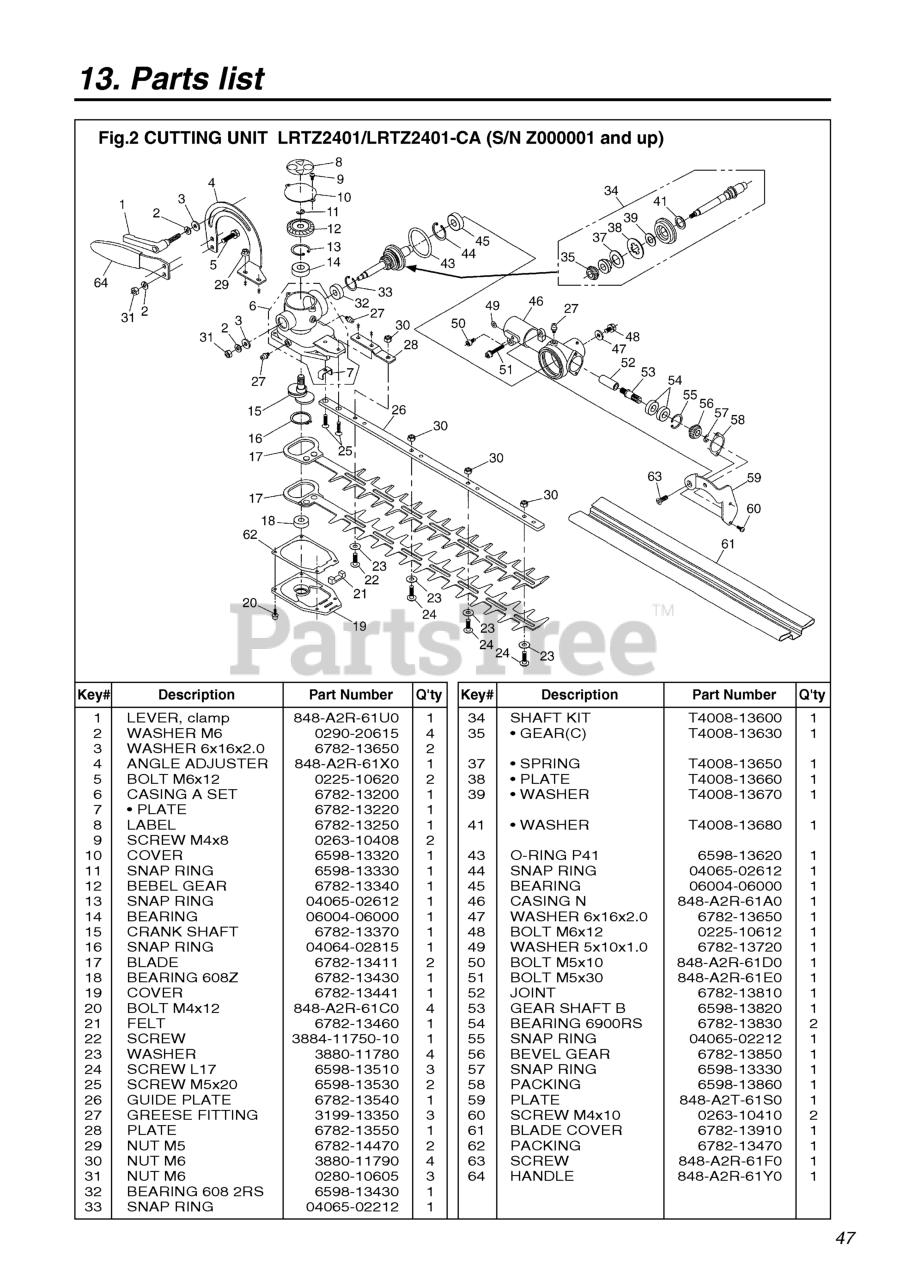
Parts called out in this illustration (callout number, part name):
1	LEVER, CLAMP
2	WASHER, M6 X 15
3	WASHER, 6X15X2.0
4	ANGLE ADJUSTER
5	BOLT
6	CASING (RPLS -13210)
7	PLATE
9	SCREW, M4 X 8
11	RING, SNAP
12	GEAR, BEVEL
13	RING, SNAP, M26 X 1.2
14	BEARING
15	CRANKSHAFT
16	RING, SNAP, M28 X 1.5
17	BLADE (RPLS -13410) 18
18	BEARING
19	COVER
20	BOLT
21	FELT
22	SCREW (RPLS 3884-11750)
23	WASHER (RPLS 3873-11760)
24	SCREW
25	SCREW, M5 X 20
26	PLATE, GUIDE
27	FITTING, GREASE
28	PLATE (RPLS 6780- )
29	NUT, M5
30	NUT, M6
31	NUT, M6 X 5
32	BEARING
33	RING, SNAP, M22 x 1.2
35	GEAR (C)
37	WASHER, SPRING
38	PLATE
39	WASHER
41	WASHER
43	O-RING
44	RING, SNAP, M26 X 1.2
45	BEARING
46	CASING N
47	WASHER, 6X15X2.0
49	WASHER
50	BOLT M5X10
51	BOLT M5X30
52	JOINT (REPLACES T3078-13810)
53	SHAFT, GEAR
54	BEARING
55	RING, SNAP, M22 x 1.2
56	GEAR, BEVEL
57	RING, SNAP
58	PACKING
59	PLATE
60	SCREW, M4 X 10
61	COVER, BLADE
62	GASKET
63	SCREW
64	HANDLE
